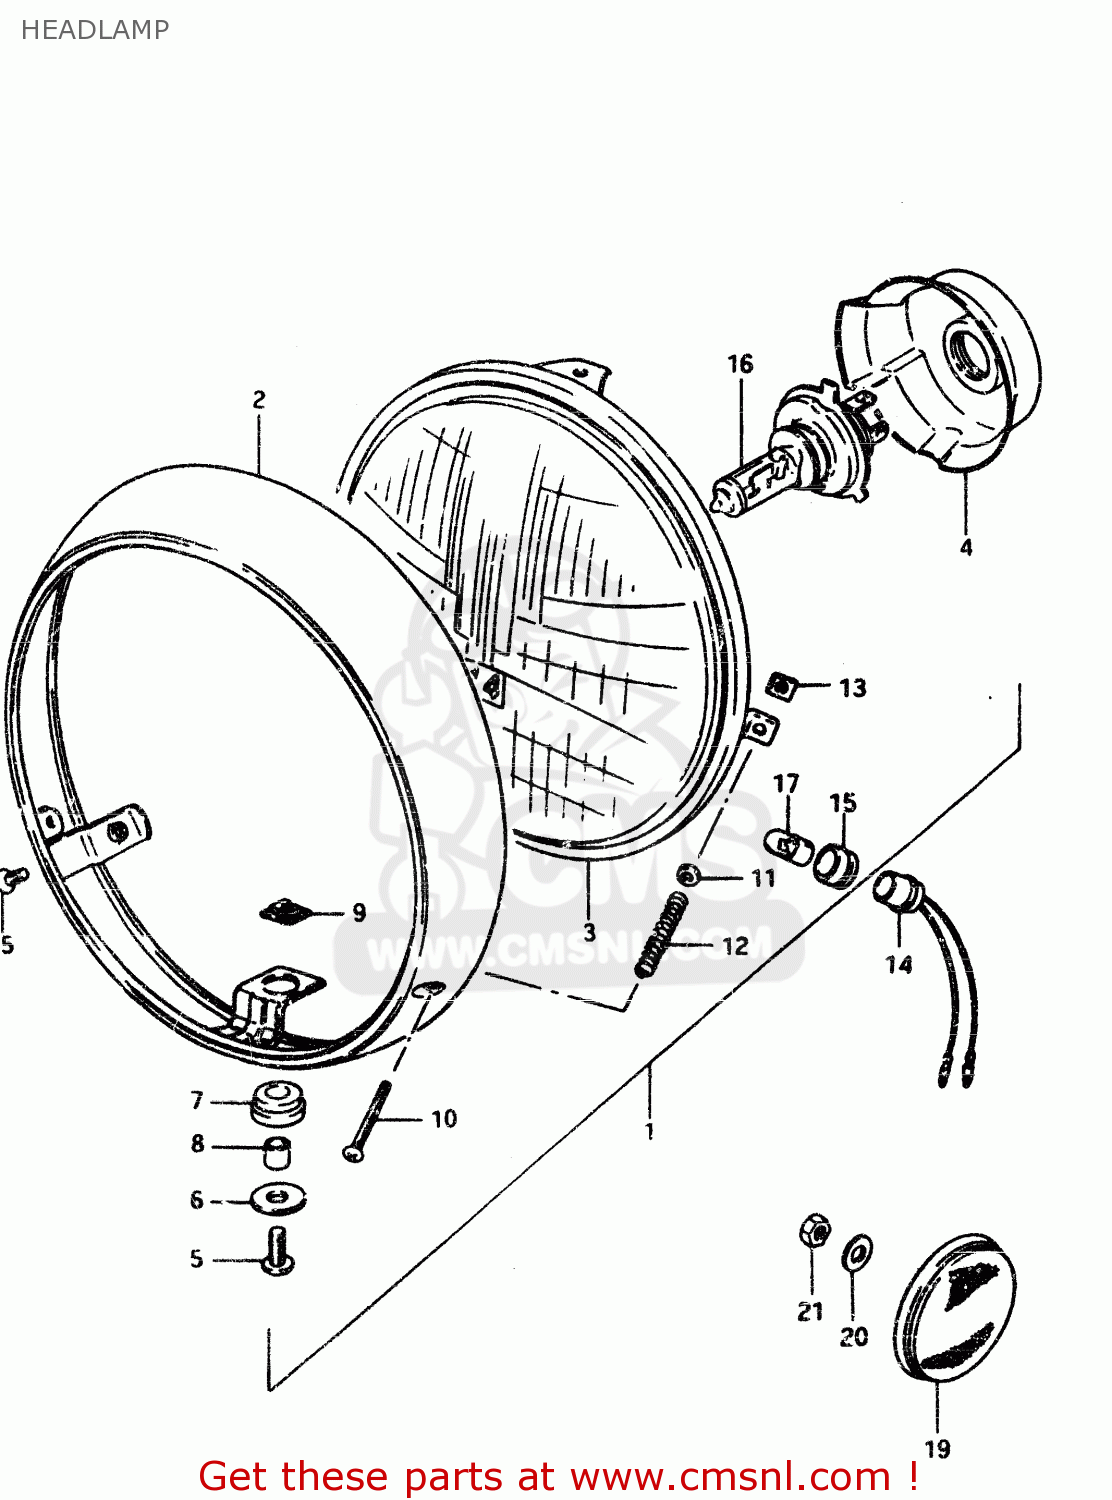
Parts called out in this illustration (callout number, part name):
1	HEADLAMP ASSY
2	RIM
3	LAMP UNIT
4	COVER,SOCKET
5	SCREW
6	WASHER
7	CUSHION
8	SPACER
9	NUT
10	SCREW
11	WASHER
12	SPRING
13	NUT,HEADLAMP ADJUSTER
14	SOCKET
15	JOINT,RUBBER
16	BULB(12V60/55W,H4)
17	BULB
18	SCREW(5X12)
19	REFLEX REFLECTOR,RR
20	WASHER
21	NUT
